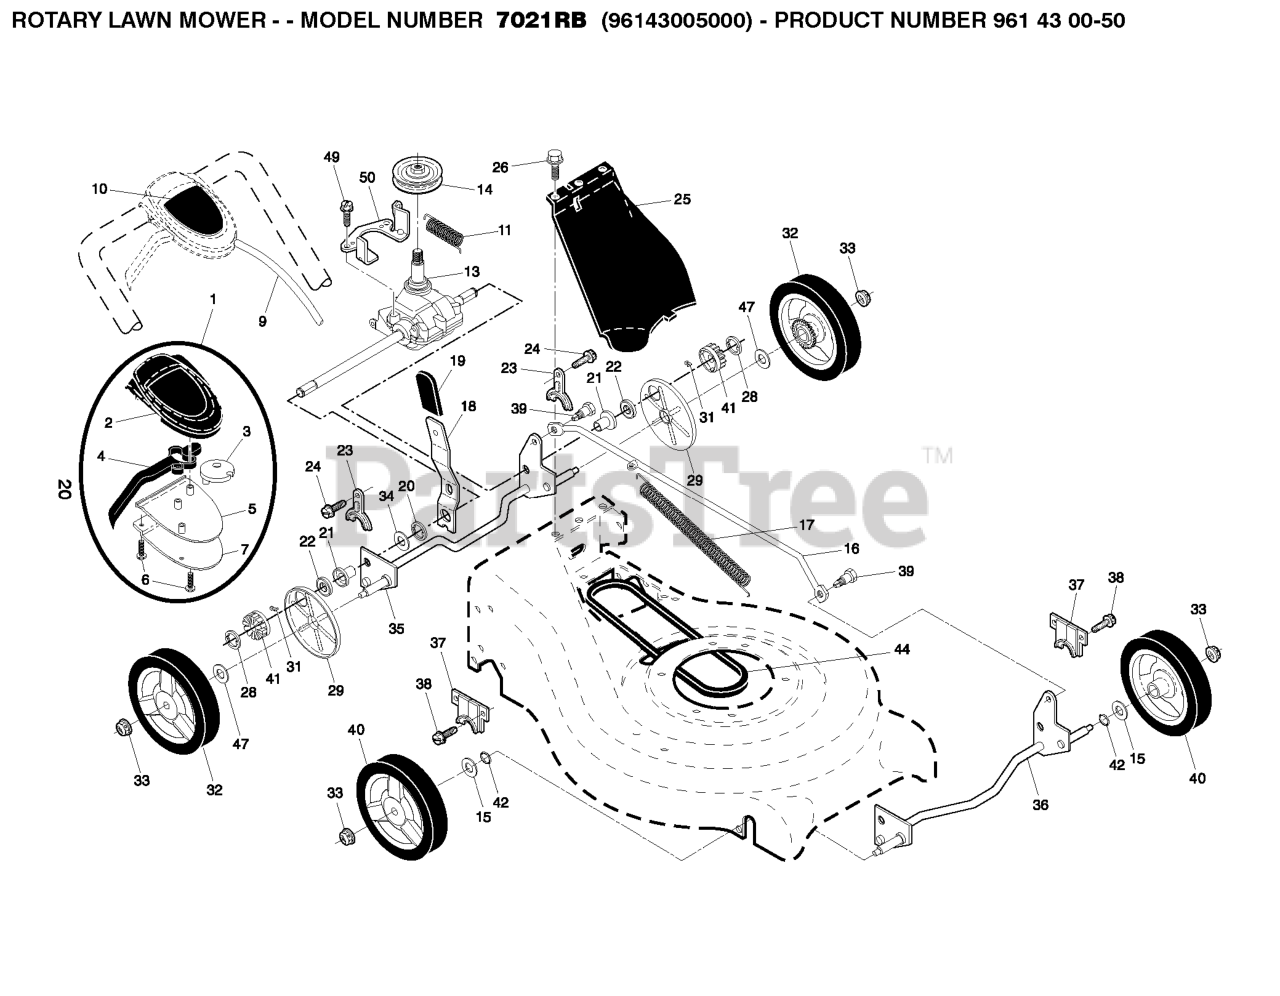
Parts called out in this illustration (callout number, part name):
1	Duo-Bal Harness
1	Harness
4	RP CLIP
5	FRONT PIECE
6	FRONT PIECE
8	HARNESS HOOK, COMPLETE
9	CATCH *
10	SPRING
11	HOOK
